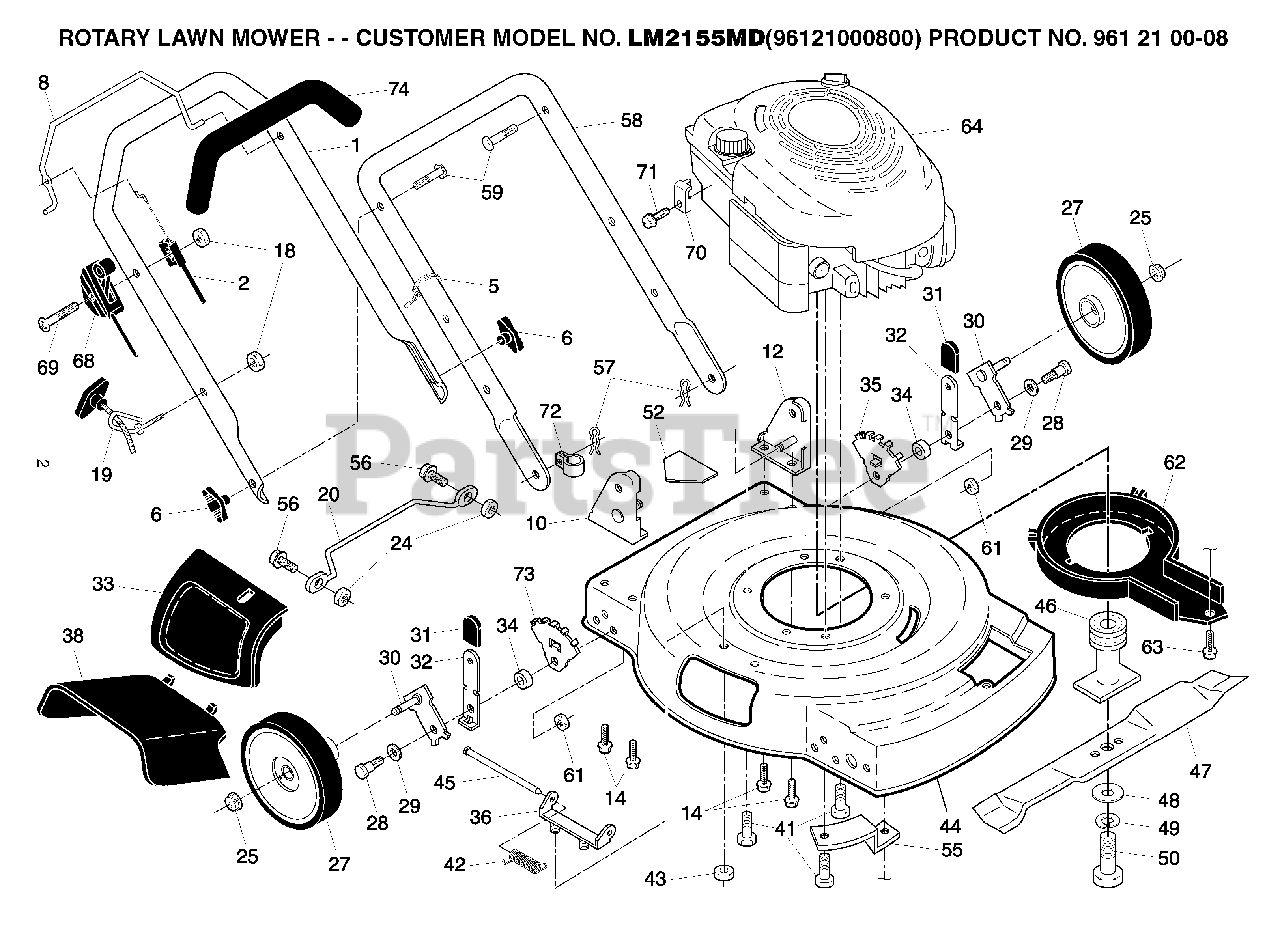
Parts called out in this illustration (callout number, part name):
2	ENGINE ZONE CONTROL CABLE
5	TIE GUIDE
6	KNOB, DEFLECTOR
10	HANDLE BRACKET ASM. RH
12	HANDLE BRACKET ASM. LH
14	SCREW 5/16-18
18	NUT
19	GUIDE.ROPE.STD.BLK.ZIN
25	HEX FLANGE LOCKNT
28	BOLT
29	BELLEVILLE WASHER
30	AXLE ARM
31	SELECTOR KNOB
34	RP SPACER HT ADJ
36	HINGE BRACKET
41	BOLT 3/8-16X1-1/8
42	TORSION SPRING
43	LOCKNUT
45	ROD.HINGE.COMBI-C
46	BLADE ADAPTOR / PULLEY
48	WASHER,HARDEN
49	LOCKWASHER
50	SCREW, HEX HD 3/8-24 X 1-3/8
52	DECAL.INTERNATIONL.CUTFINGER
55	BRACKET
57	HAIRPIN COTTER
59	BOLT, HANDLE 5/16-18X1.75
61	LOCKNUT PM
62	DEBRIS.SHIELD.21:.FGD
63	SCREW.HEX.WSH
68	THROTTLE CONTROL
70	CABLE CLAMP(ENGINE)
71	SCREW.HEX.HEAD.WASHER.10-16
72	CLIP.CABLE.BLK
74	GRIP.HANDLE.FOAM
